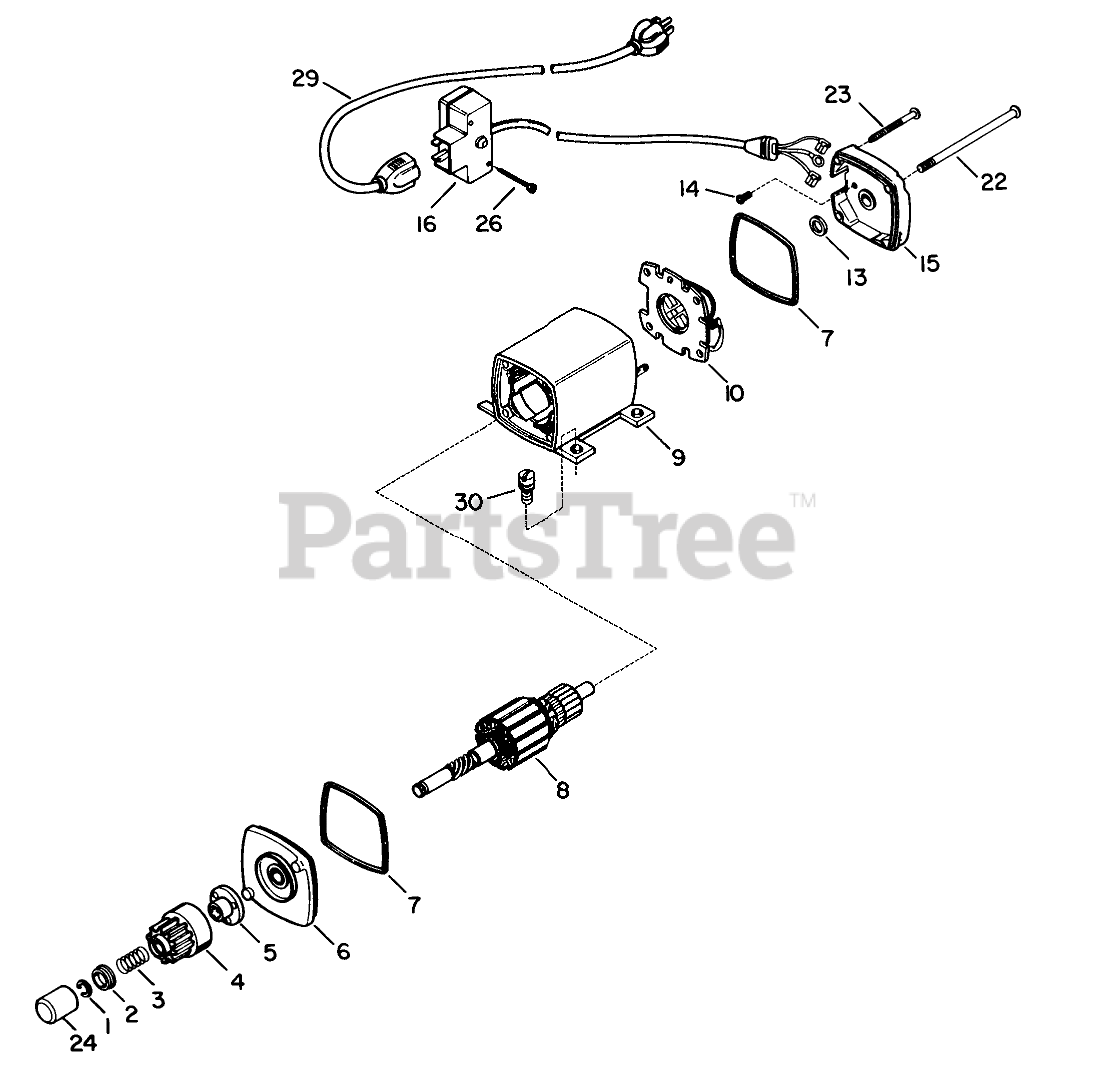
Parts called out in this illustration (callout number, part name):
1	Ring-Retainer
2	Retainer-Spring
3	Spring-Anti Drift
5	Nut-Engaging
6	Cap Assy., Drive End (Incl. Ref. #7)
8	Armature
9	Housing ASM
10	Card ASM
13	Washer-Thrust
14	Screw-Ground
15	Cap Assembly, Commutator End (Incl. Ref. #7)
16	Switch Box ASM
22	Bolt-Case
23	Screw-Ground
24	Cover-Dust
29	Cord-Extension
